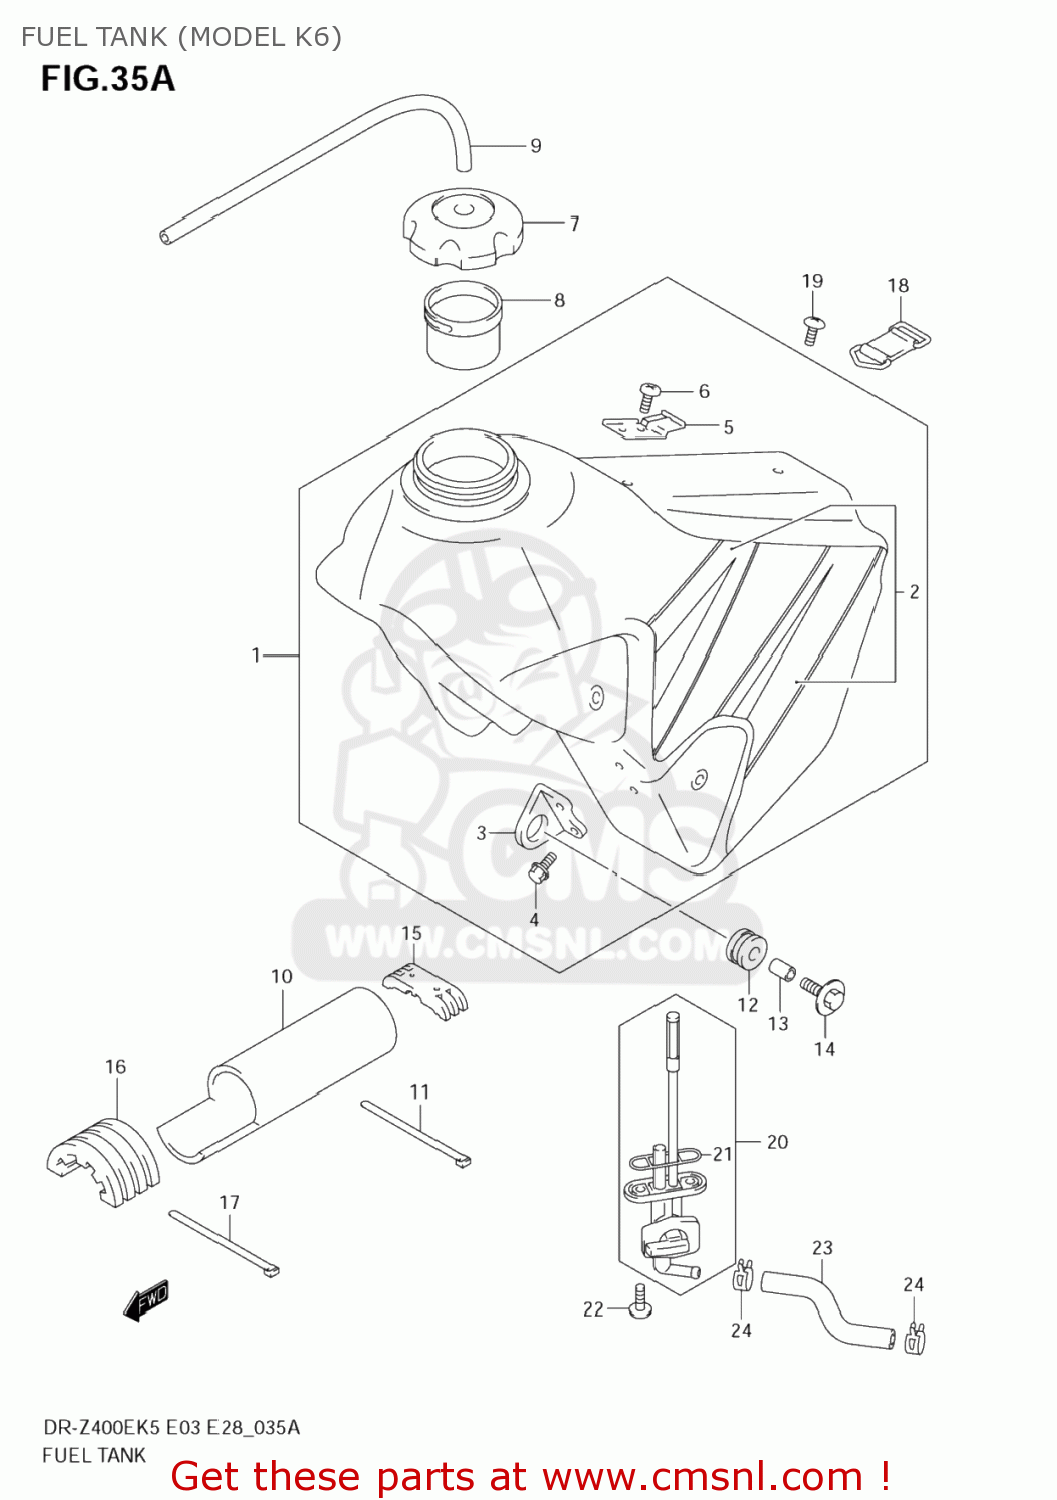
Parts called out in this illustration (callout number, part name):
1	TANK ASSY,FUEL(YELLOW)
2	TAPE SET,FUEL TANK
3	BRACKET,FUEL TANK FR
4	BOLT
5	HOOK,SEAT FR
6	SCREW 6X12
7	CAP ASSY,FUEL TANK FILLER
8	TUBE,FILLER INLET
9	HOSE(5X8.2X600)
10	SHIELD,FUEL TANK
11	CLAMP(L:300)
12	CUSHION,MUFFLER
13	SPACER(6.5X9X13.5)
14	BOLT(6X30)
15	CUSHION,FUEL TANK RR
16	CUSHION,FUEL TANK
17	CLAMP(L:300)
18	BAND,FUEL TANK RR
19	SCREW
20	COCK ASSY,FUEL
21	GASKET,JOINT (NAS)
22	BOLT
23	HOSE,FUEL
24	CLIP
